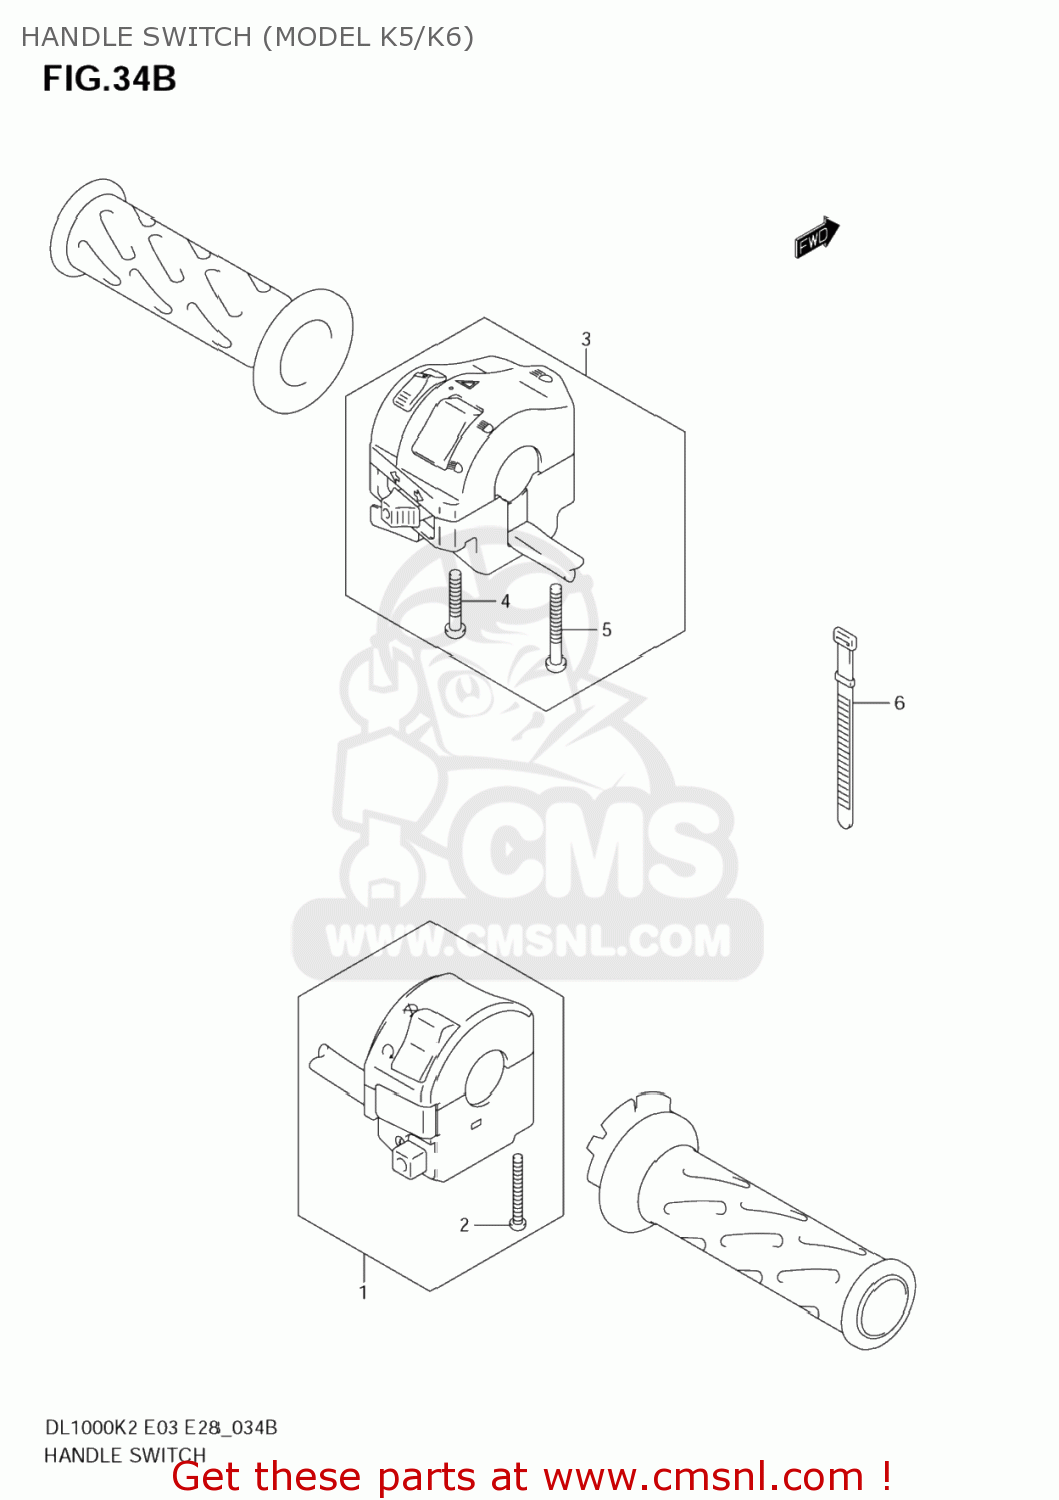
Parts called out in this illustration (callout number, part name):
1	SWITCH ASSY,HANDLE,R
2	SCREW
3	SWITCH ASSY,HANDLE,L
4	SCREW
5	SCREW
6	CLAMP(L:120)
